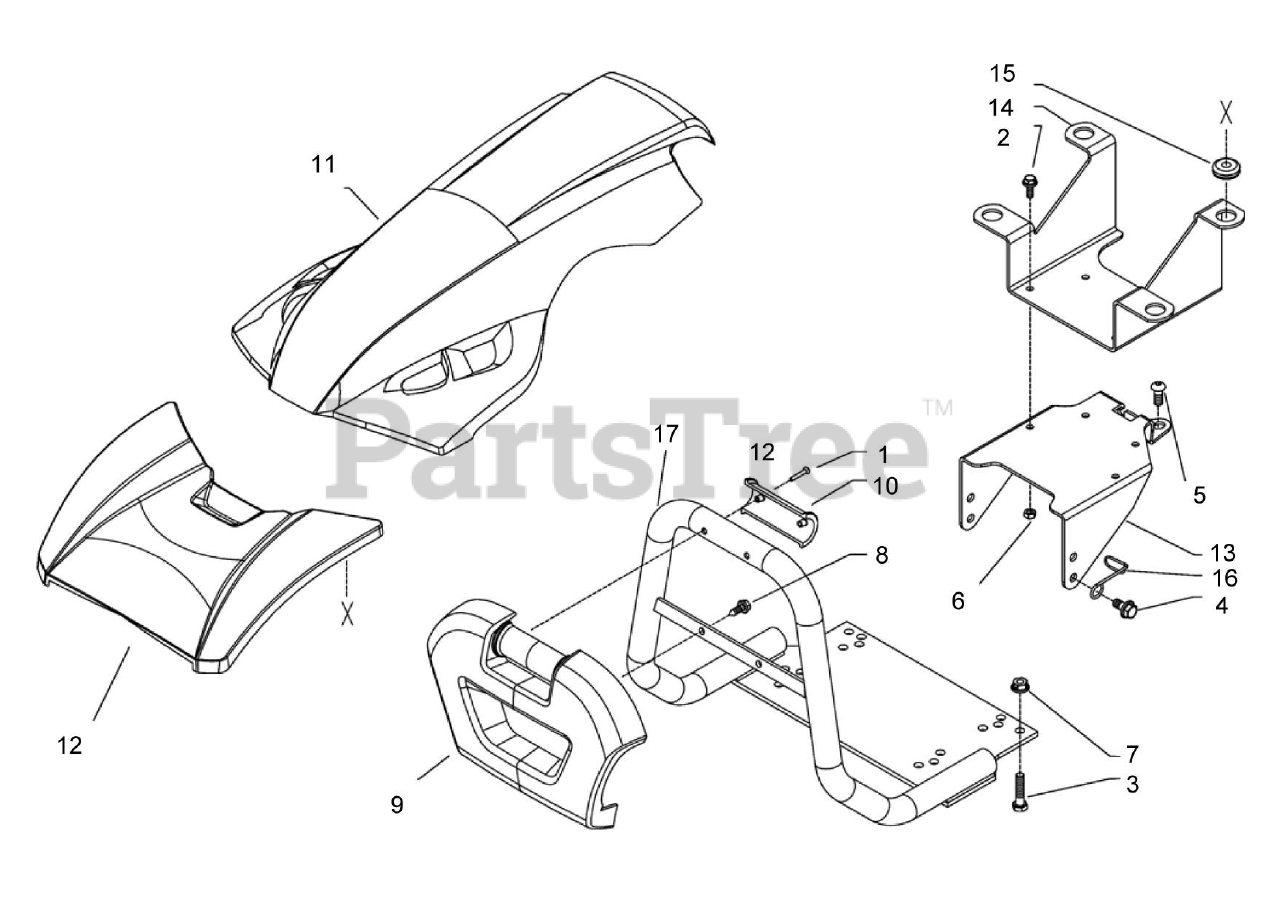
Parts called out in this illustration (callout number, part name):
1	SCREW, 5X25
2	SCREW, HEX M6X16
3	CAPSCREW, M8X40
4	SCREW, TE M8X16
5	SCREW, M10X16
6	LOCKNUT, M6 STANDARD
7	LOCKNUT, M8 FLANGED
8	SCREW ,TAPPING M6 3X19
9	BUMPER, FRONT
10	HALF BEARING
11	COVER, HANDLE BAR
12	GUARD, LOWER
13	BRACKET
14	SUPPORT, GUARD
15	SUPPORT, CAP BODY GUARD
16	GUIDE, CABLE
17	BUMPER HONDA GX340
